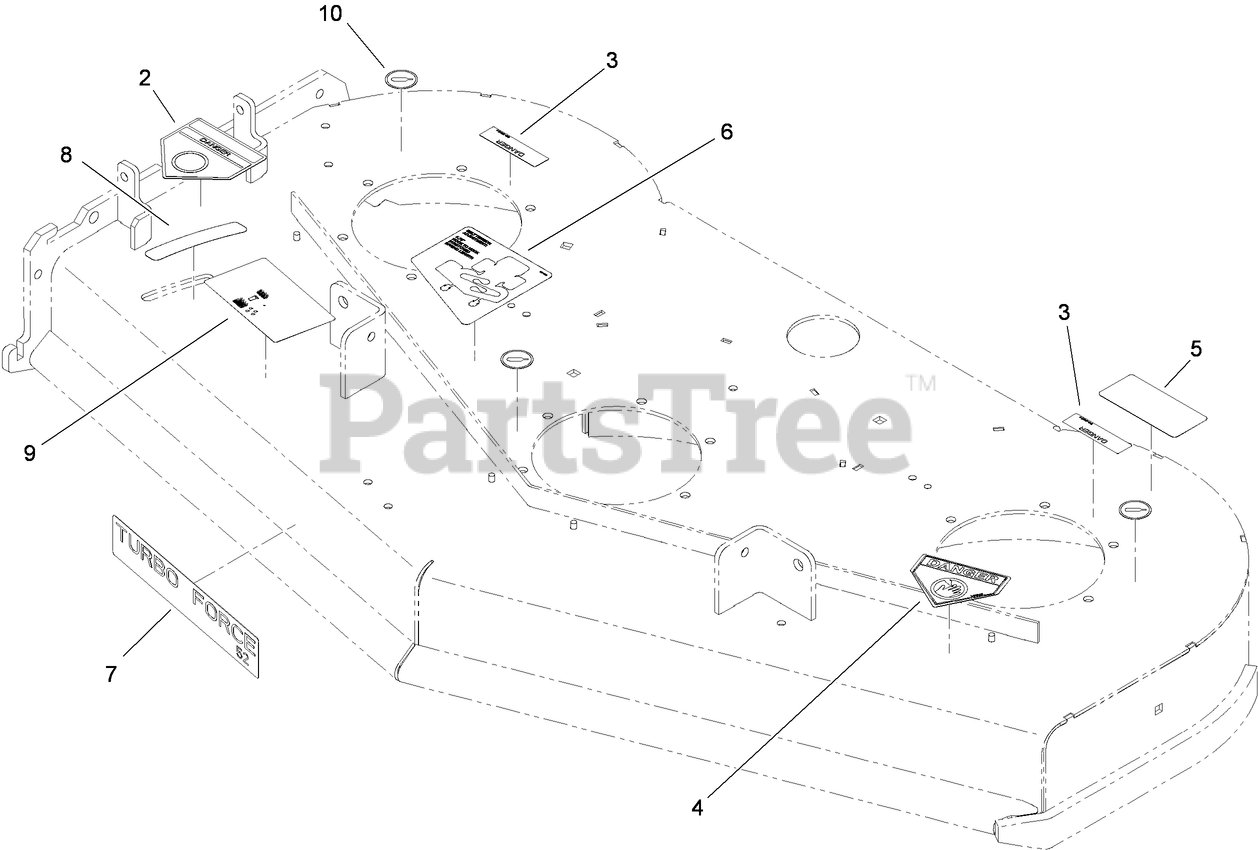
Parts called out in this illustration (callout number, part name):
2	DECAL-DANGER
3	DECAL-COVER, MISSING
4	DECAL-DANGER
5	DECAL-TORQUE
6	DECAL-TENSION, BELT
8	DECAL-SETTING, BAFFLE
9	DECAL-ADJUSTMENT, BAFFLE
10	DECAL-GREASE
